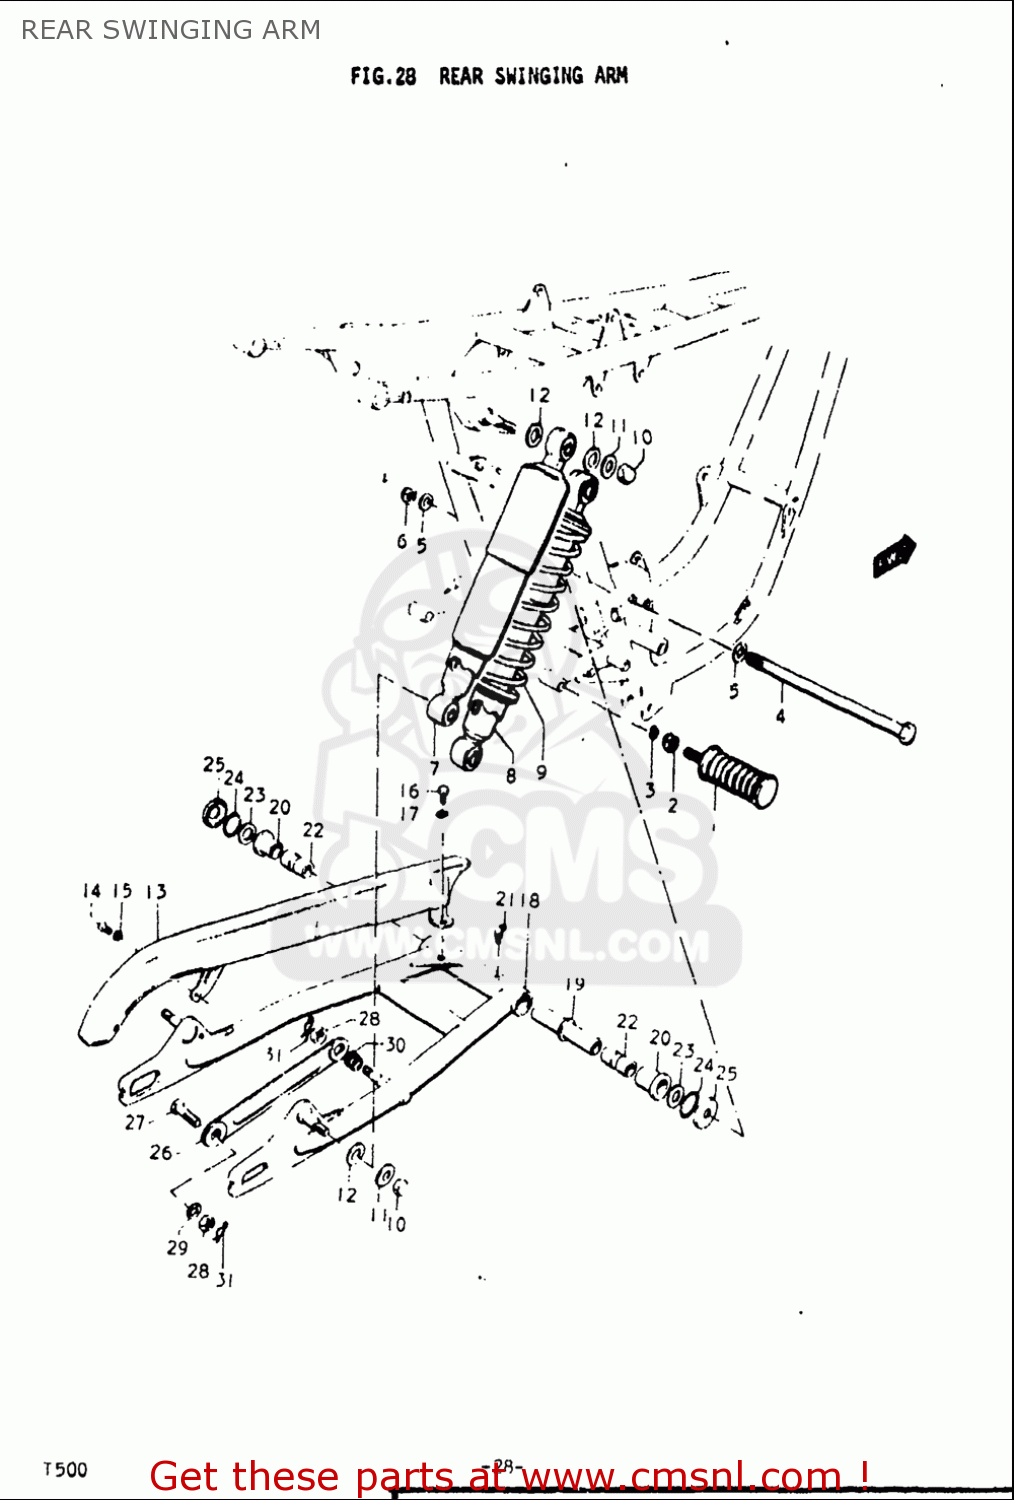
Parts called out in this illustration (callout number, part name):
1	FOOTREST SET,PILLION
2	NUT
3	WASHER,LOCK
5	WASHER
10	NUT
11	WASHER
12	WASHER (10.5X24X2.3)
14	SCREW(5X12)
15	TOOTHED WASHER
16	BOLT
17	WASHER,LOCK
20	BUSH
21	NIPPLE,GREASE
22	SPACER
23	WASHER(14.5X29X2.3)
24	O RING(D:3,ID:29.5)
25	COVER
27	BOLT(10X31)
28	NUT
29	WASHER,LOCK
30	SPRING
31	CLIP
